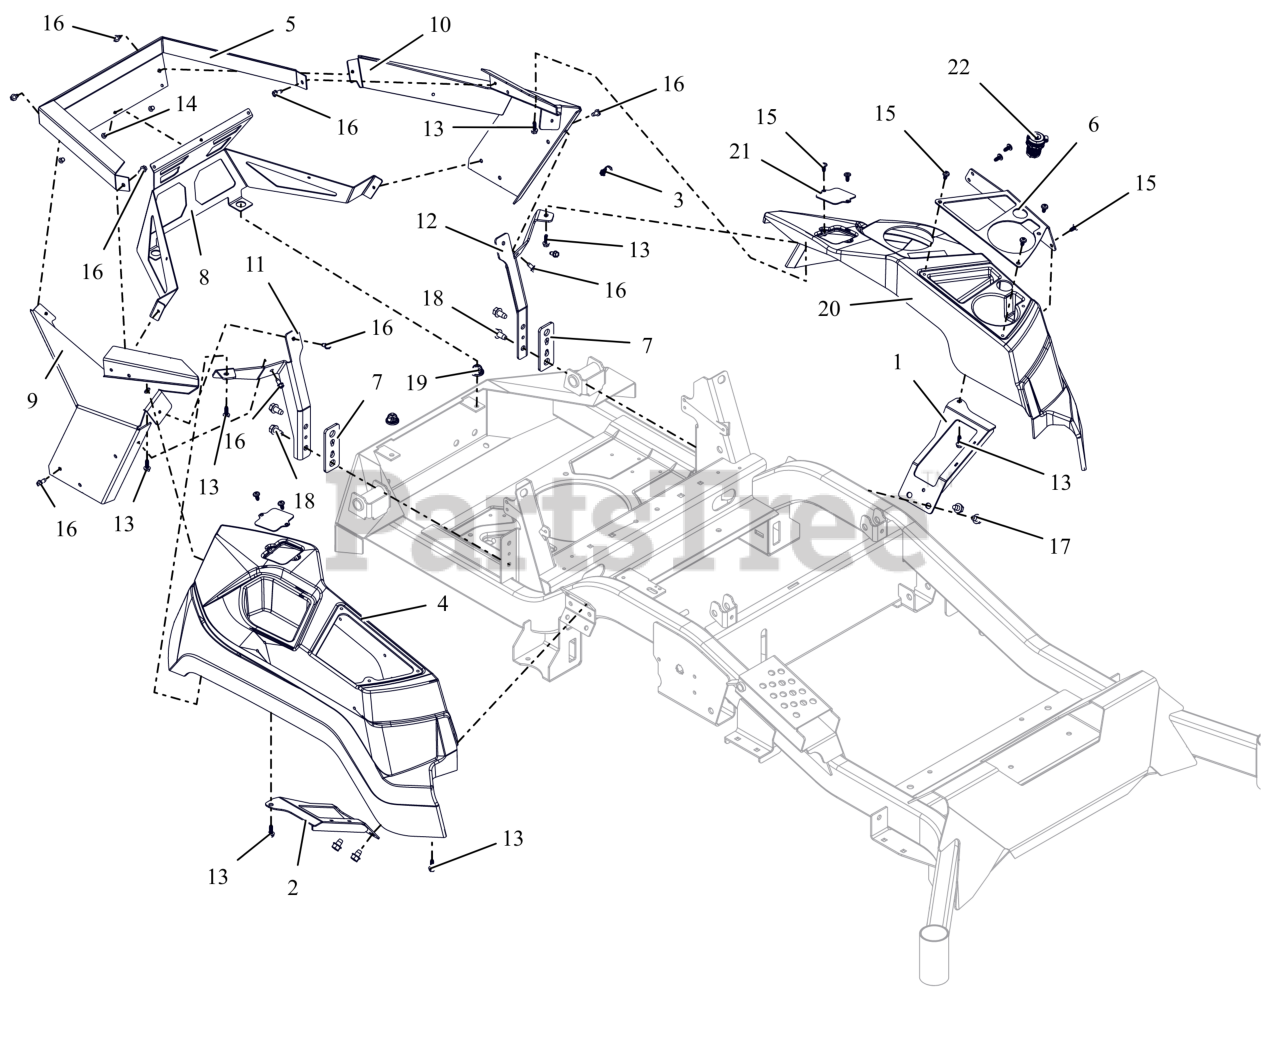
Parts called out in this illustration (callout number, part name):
1	WLDMT, LH FENDER MOUNT
2	WLDMT, RH FENDER MOUNT
3	CLIP, CABLE GUIDE
4	FENDER, RH APEX - 2017
5	GUARD- ENGINE WRAP
6	PLATE-APEX CUP HLDR W/USB(ORG)
7	PLATE- CONTROL PANEL SPACER
8	GUARD, ENGINE
9	PANEL- RH REAR FENDER MOUNT
10	PANEL- LH REAR FENDER MOUNT
11	BRKT- RH FENDER MOUNT
12	BRKT- LH FENDER MOUNT
13	SCR, PLASTITE .25-10X.75 ZCC
14	RIVET, .1875 AL/AL .126-.250
15	SCR-PAN .25-15X.50 6L H/LZB500
16	SCR-TAP .25X.50 HWH ZB500
17	SCR,TAP .375-16X.50 HWH TR ZCC
18	SCR,TAP .375-16X.75 HWH TR ZCC
19	GROMMET, 10MM BOLLHOFF
20	FENDER, LH APEX
21	PLATE, ROPS HOLE-HD
22	USB, DUAL PORT USB-C, 12V BLK
